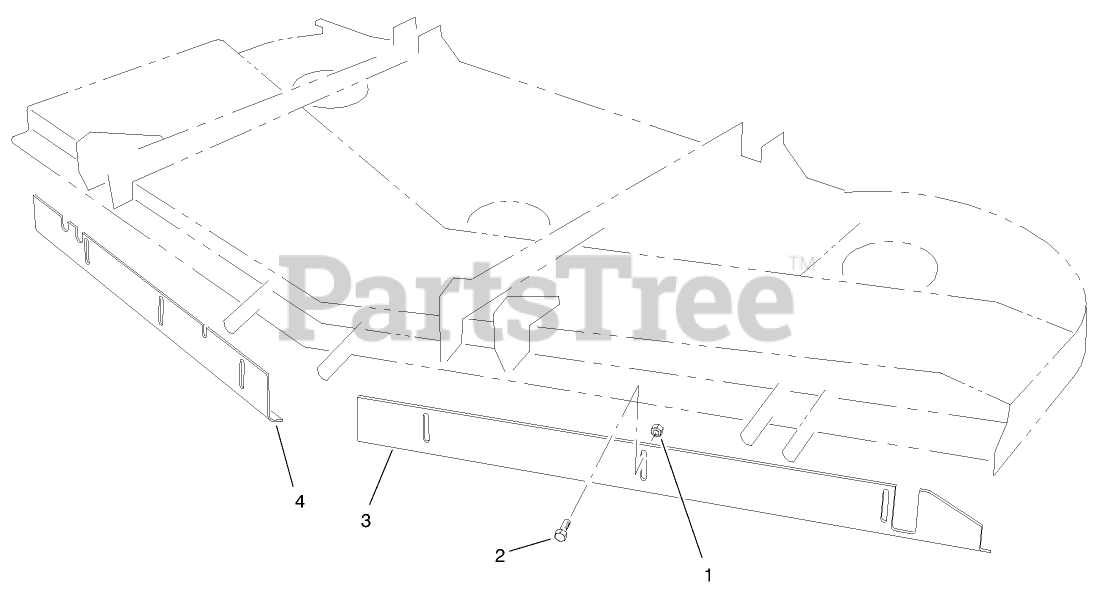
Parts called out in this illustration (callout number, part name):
1	NUT-HF
2	SCREW-HH
3	Baffle-Front
4	Baffle-Front
